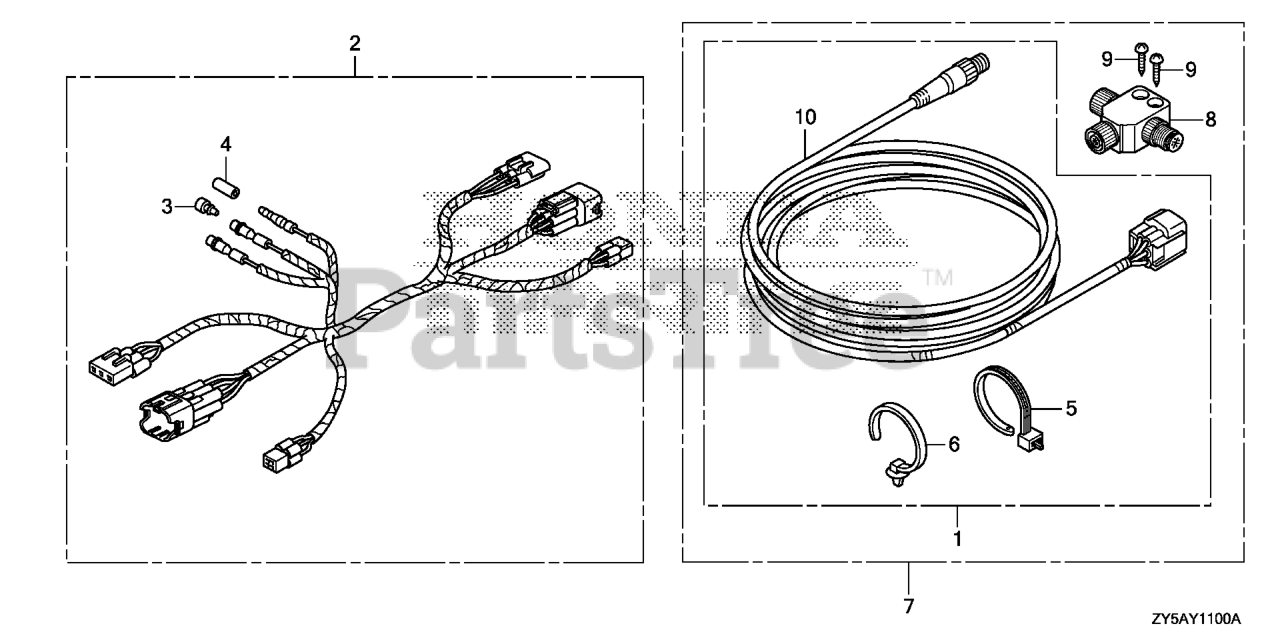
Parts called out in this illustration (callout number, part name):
1	KIT, CABLE (6FT) (NMEA)
2	HARNESS ASSY., REMOTE CONTROL SUB (ENGINE NO.)
3	PLUG, CONNECTOR (INNER) (TROLLING CONTROL)
4	PLUG, CONNECTOR (OUTER) (ENGINE NO.)
5	TIE, CABLE
6	CLIP, HARNESS BAND (155.3MM) (BLACK)
7	KIT, CABLE (6FT) (NMEA)
7	CABLE KIT, INTERFACE
8	CONNECTOR (T)
9	SCREW, TAPPING (4X25)
10	CABLE ASSY., INTERFACE (6FT)
